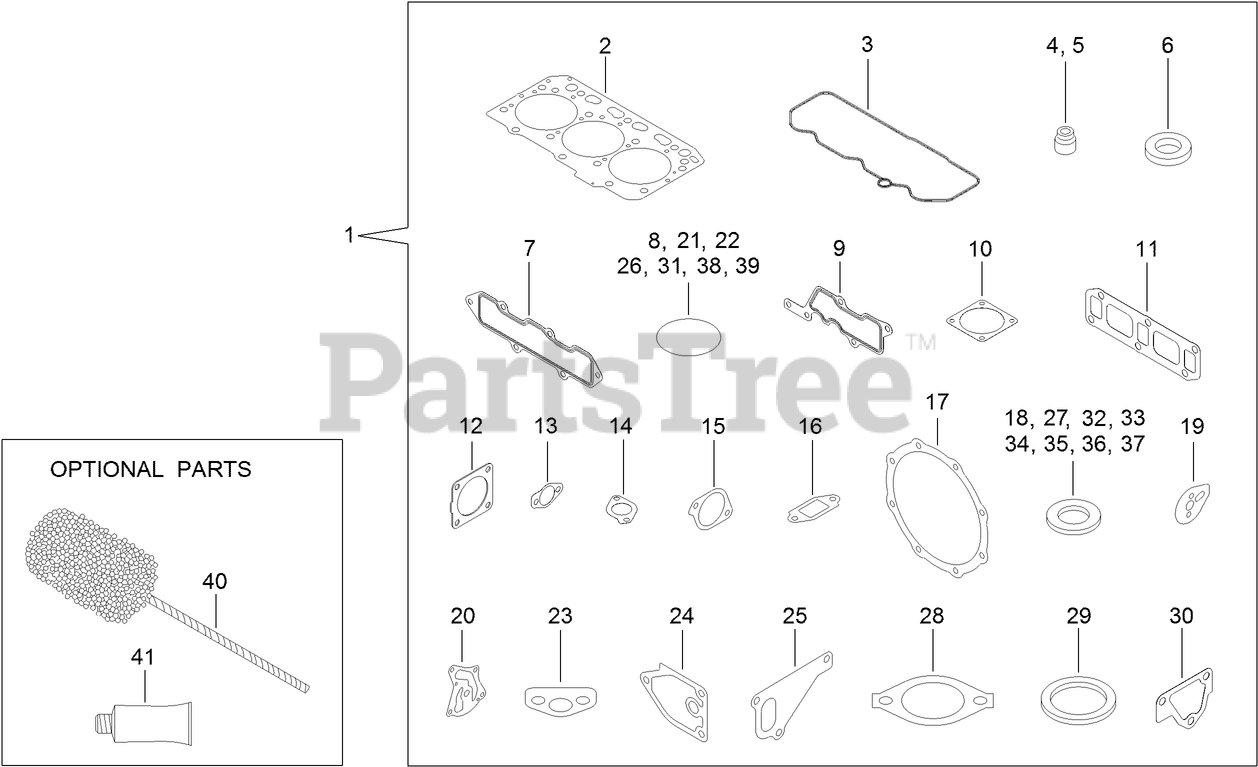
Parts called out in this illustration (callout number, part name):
1	GASKET KIT
2	HEAD GASKET ASM
3	GASKET-HEAD, CYLINDER
4	SEAL-STEM, VALVE
5	SEAL-STEM, VALVE
6	GASKET-INJECTOR
7	GASKET-MANIFOLD, INTAKE
8	O-RING
9	GASKET-COLLECTOR
10	GASKET-THROTTLE
11	GASKET-MANIFOLD, EXHAUST
12	GASKET
13	GASKET-COOLER, E G R
14	GASKET
15	GASKET-INTAKE VALVE, E G R
16	GASKET-OUT VALVE, E G R
17	GASKET-D P F
18	GASKET-SENSOR
19	GASKET-IDLE, SHAFT B
20	GASKET
21	O-RING
22	O-RING
23	GASKET
24	GASKET
25	GASKET
26	O-RING
27	GASKET
28	GASKET
29	GASKET
30	GASKET
31	O-RING
32	WASHER-SEAL
33	WASHER-SEAL
34	WASHER-SEAL
35	WASHER-SEAL
36	GASKET
37	GASKET
38	O-RING
39	O-RING
41	GASKET-LIQUID
